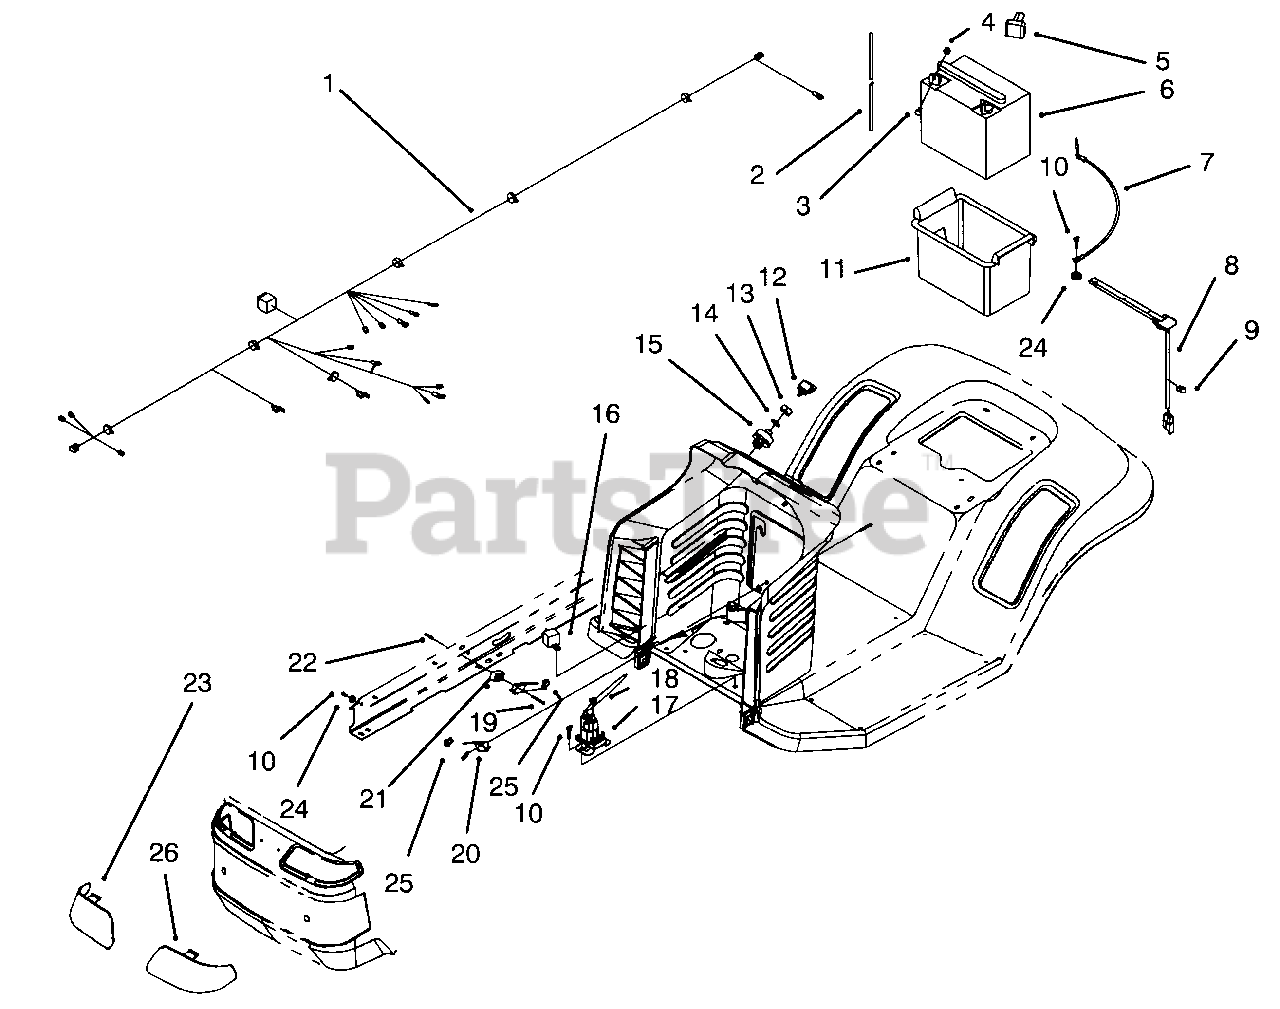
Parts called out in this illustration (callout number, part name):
1	Harness-Wire
2	Vent-Tube
3	Screw-Hex Hd. Cap
5	Boot-Battery Terminal
6	Battery-7 Plate
7	Cable-Battery Negative
8	Switch-Seat
9	Clip-Wire Retainer
10	Screw-Hex Hd. Thr'd Forming
11	Box-Battery
12	Key-Ignition
14	Washer-Lock
15	Switch-Ignition (Incl. Ref. #13 & 14)
17	Solenoid
18	Nut-Keps
19	Screw-Phillips Hd.
20	Switch-Micro
21	Spacer-Microswitch
23	Lens-R.H.
24	Washer-Ext. Tooth Lock
25	Seal-Plunger
26	Lens-L.H.
